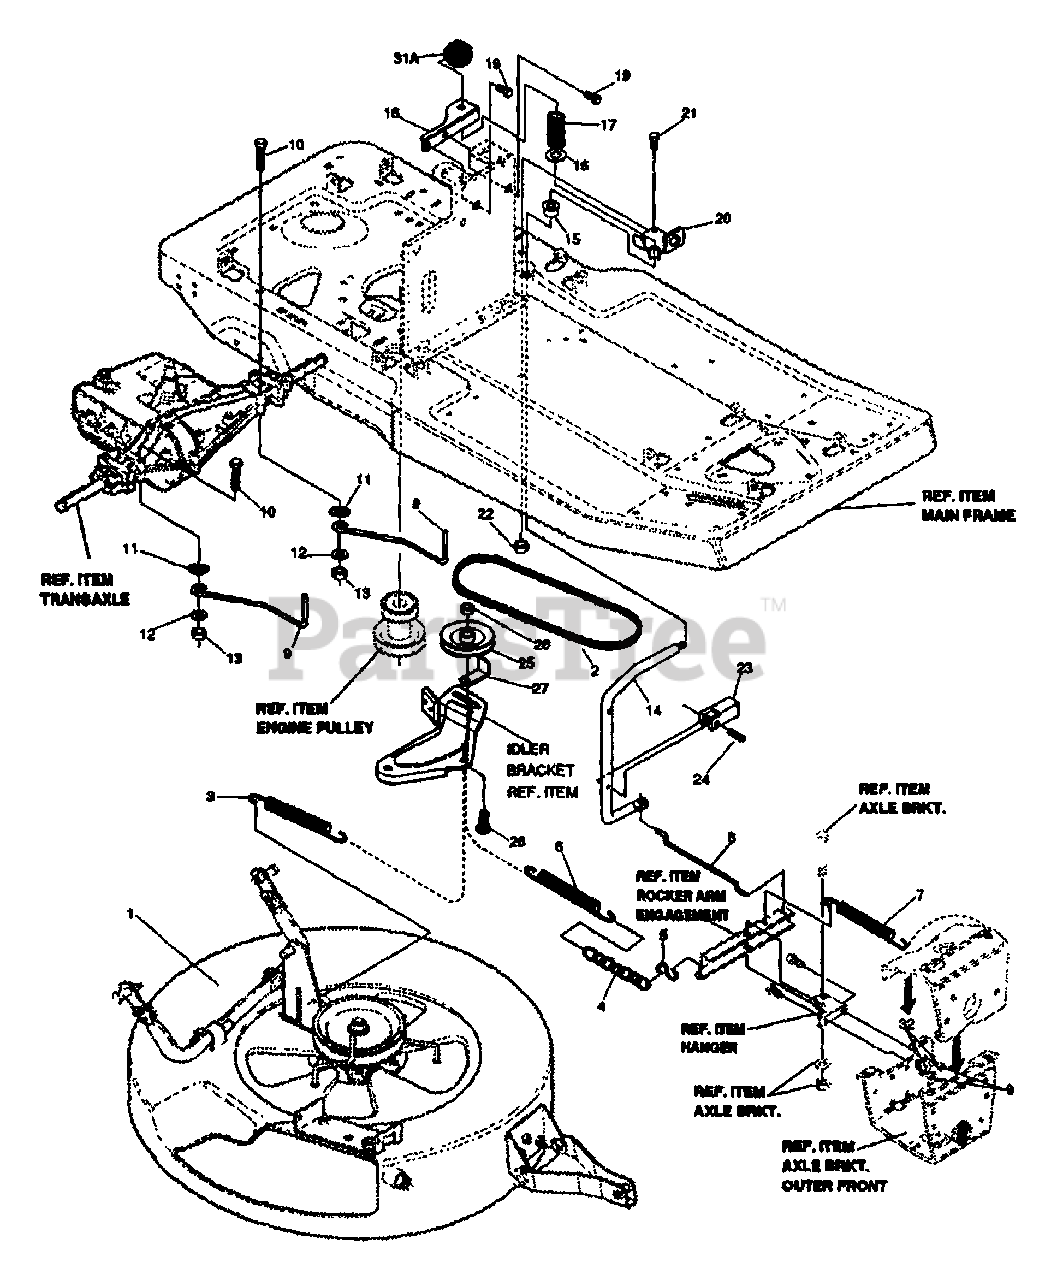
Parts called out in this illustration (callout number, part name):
2	BELT, V 4L 50.5 LG
3	SPRING .071 X .62 X 4.37
4	CHAIN, JACK
5	HOOK, S, 10 GA. STEEL
6	SPRING, .75 X 6.3 X .105 TENSION
8	SCREW, 5/16-18 X .63 HHC
9	NUT, 5/16-18 REG HEX CTR LK
10	ROCKER ARM, MOWER ENGAGEMENT
11	BOLT .500 X 1.18 HHSH 3/8-16
12	WASHER FLAT .390 X 1.25 X .119
13	NUT, 3/8-16 REG HX CTR LK
14	SPRING .071 X .62 X 4.37
15	ROD, CONNECTING
16	GUIDE, BELT
17	SCREW, 5/16-18 X 2.50 HHC
18	WASHER, EXLK .320 X .61 X .03
19	WASHER, FLAT .344 X .60 X .065
20	NUT, 5/16-18 REG HEX CTR LK
21	HANDLE, MOWER ENGAGEMENT
22	BEARING, FLANGED, NYLON
23	RETAINER,SPRING
24	SPRING COMPRESSION
25	SUPPORT BRACKET PTO
26	SCREW, 1/4-20 X .50 WA HH TAP
27	BRACKET, PTO LIMIT
28	SCREW, 5/16-18 X .75 WA HH TAP
29	NUT, 5/16-18 REG HEX CTR LK
30	STOP,PTO ENGAGEMENT
31	PIN, SPRING .187 DIA X 1.12 LG
31A	SHIFT KNOB
32	WASHER, FLAT .344 X .69 X .065
33	PULLEY, IDLER V4L 3.06 X .72
34	BOLT, 30-16 X 1.50 CARR GR2 Z
35	RETAINER, BELT
36	NUT, 3/8-16 REG HX CTR LK
